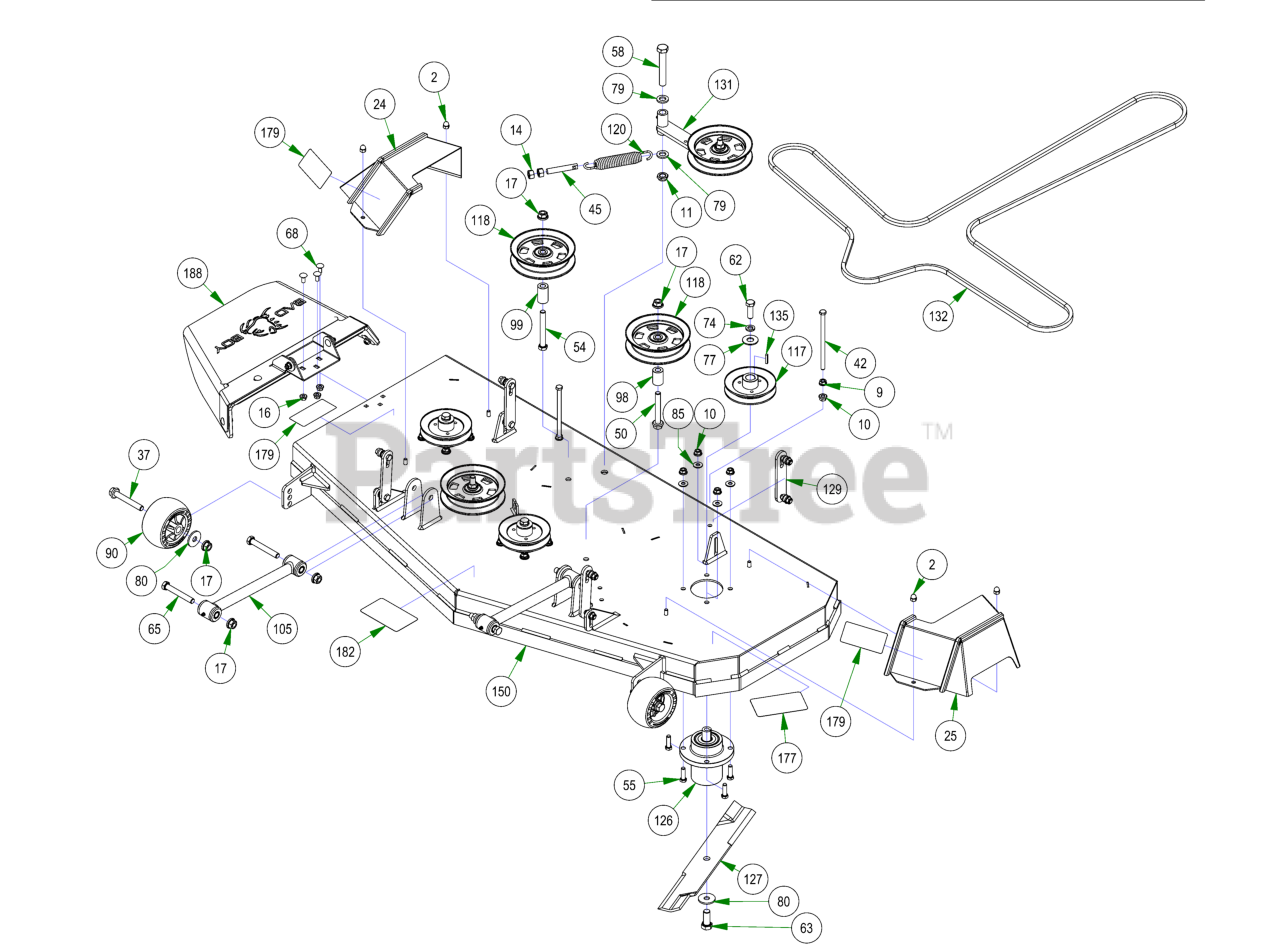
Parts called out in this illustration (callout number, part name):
2	5/16-18 ACORN NUT HIGH-CROWN ZC
9	3/8-16 HEX SERRATED FLANGE NUT HARD/ZINC
10	3/8-16 NYLON INSERT FLANGE LOCKNUT (GR.F) ZINC
11	5/8-11 NYLON INSERT JAM LOCKNUT ZINC
14	1/2-13 HEX NUT ZINC
16	5/16-18 NYLON INSERT FLANGE LOCKNUT ZINC
17	1/2-13 NYLON INSERT FLANGE LOCKNUT ZINC
24	2021 Maverick 54”/60” RH Pulley Cover
25	2021 Maverick 54”/60” LH Pulley Cover
37	1/2-13 X 90MM HEX FLANGE BOLT W/SHOULDER (GR.8) ZINC
42	3/8-16 X 6.5 HEX CAP SCREW (GR.5) ZINC
45	All Thread
50	1/2-13 X 3-1/2 HEX FLANGE BOLT (GR.8) ZINC
54	1/2-13 X 4 HEX CAP SCREW (GR.8) ZINC YELLOW
55	3/8-16 X 1-1/4 HEX CAP SCREW (GR.5) ZINC
58	5/8-11 X 4 HEX CAP SCREW (GR.8) ZINC YELLOW
62	1/2-20 X 1-1/2 HEX CAP SCREW (GR.5) ZINC
63	5/8-18 X 1-1/2 HEX CAP SCREW (GR.8) ZINC YELLOW
65	1/2-13 X 3-1/2 HEX CAP SCREW (GR.5) ZINC
68	5/16-18 x 3/4 Carriage Bolt
74	1/2 SPLIT LOCKWASHER (GR.8) ZINC/YELLOW
77	5/8 USS FLAT WASHER (1-3/4" OD) GR.8 ZINC YELLOW
79	.635 ID X 1.120 OD X .140 THICK FLAT WASHER NYLON
80	1/2 BELLEVILLE WASHER (1-5/8 OD X .140 THK) ZINC
85	5/16 USS FLAT WASHER (7/8 OD) ZINC
90	Deck Wheel
98	.502 ID X .750 OD X 1.500 Long Spacer
99	1 3/4" Pulley Spacer
105	Hybrid Turnbuckle/Deck Locator
117	54 MZ Spindle Pulley
118	5-3/4 Idler Pulley
120	Deck Idler Spring
126	Spindle Assembly-MZ
127	54" Fusion Blade for ZT/Mav/Outlaw/Revolt
129	Deck Hanger Assembly
131	2017 MZ/ZT Deck Idler Assembly
132	B155.75 Deck Belt
135	3/16 X 1 SQ MACHINERY KEY 1018 STL ZINC
150	2023 54" x 4" Deck
177	2018 54" Deck Decal
179	Danger Decal-Spindle/Discharge
182	Deck Belt Route Decal
188	MZ Discharge Chute Assembly
